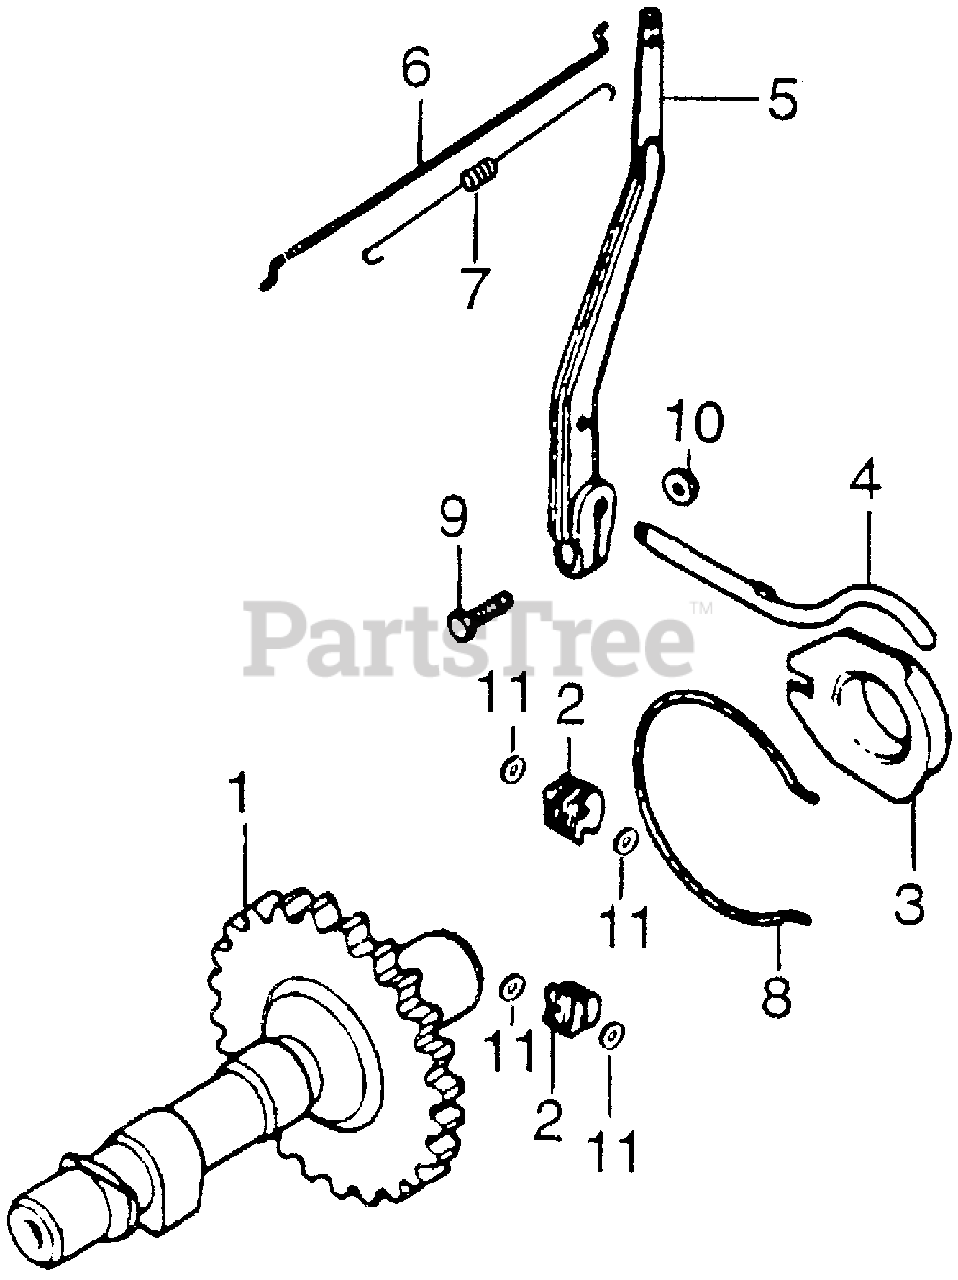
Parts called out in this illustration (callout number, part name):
1	CAMSHAFT (S)
2	WEIGHT, GOVERNOR (NOT AVAILABLE)
3	SLIDER, GOVERNOR
4	SHAFT, GOVERNOR ARM
5	ARM, GOVERNOR
6	ROD, GOVERNOR (NOT AVAILABLE)
7	SPRING, THROTTLE RETURN
8	CENTER, GOVERNOR WEIGHT
9	BOLT, HEX. (6X20)
10	NUT, FLANGE (6MM)
11	WASHER, PLAIN (3MM)
